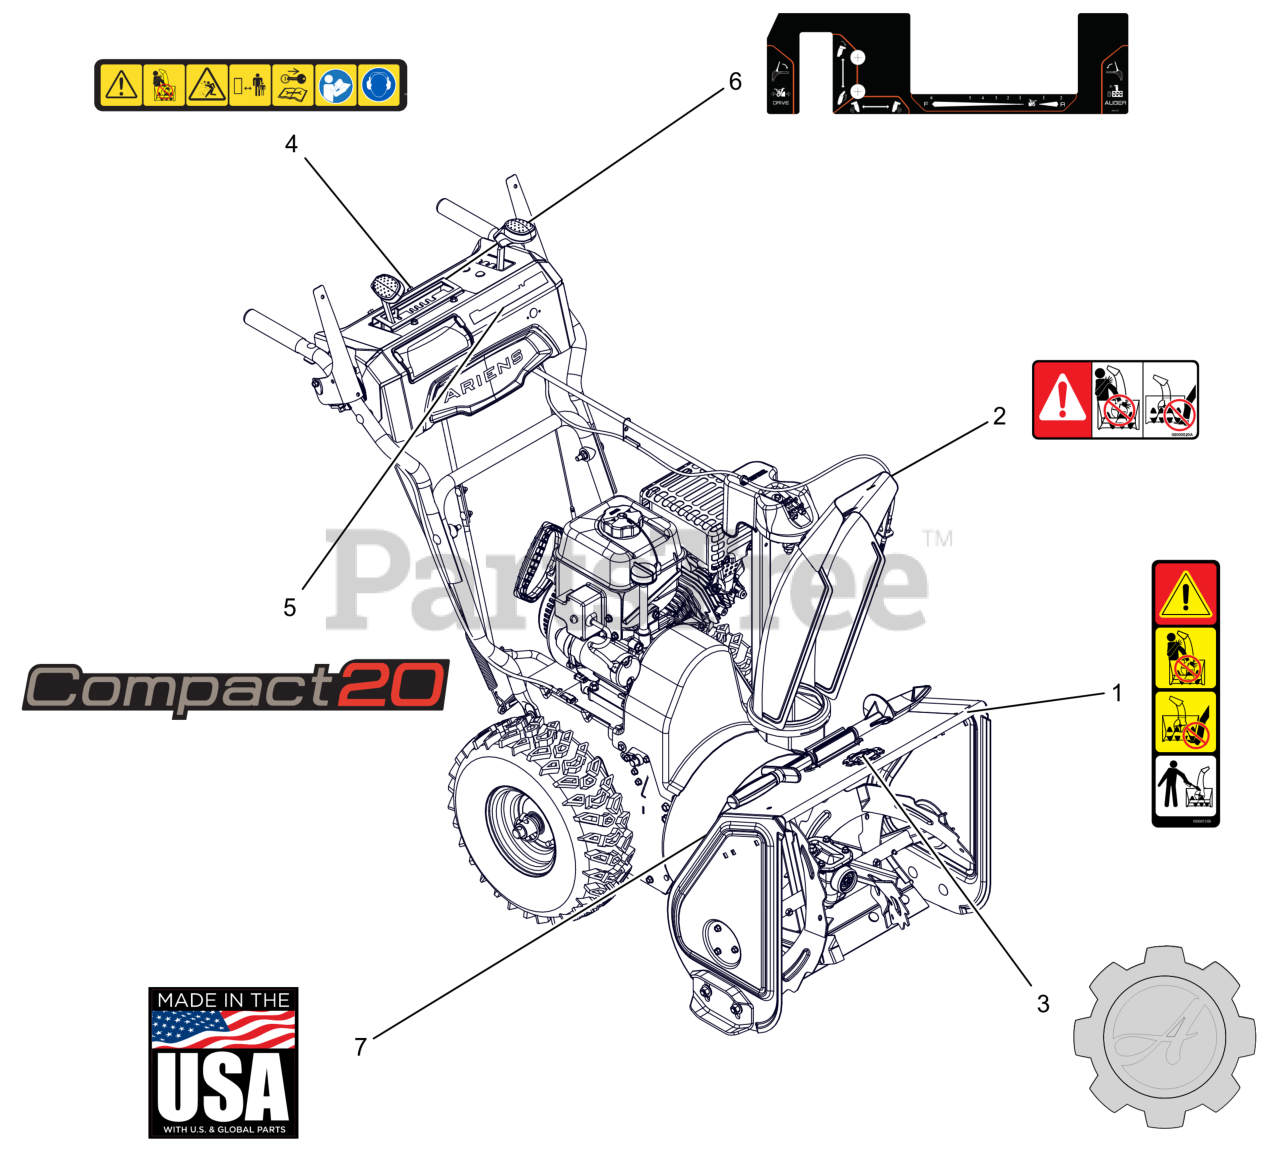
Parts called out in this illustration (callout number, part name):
1	DECAL, DANGER - ROTATING PARTS
2	DECAL, DANGER
3	DECAL, ARIENS-GEAR BADGE -THK
4	DECAL,DASH - SAFETY
5	DECAL, DASH - COMPACT 20
6	DECAL,CONTROL-COMP REMOTE
7	DECAL, MADE IN USA
